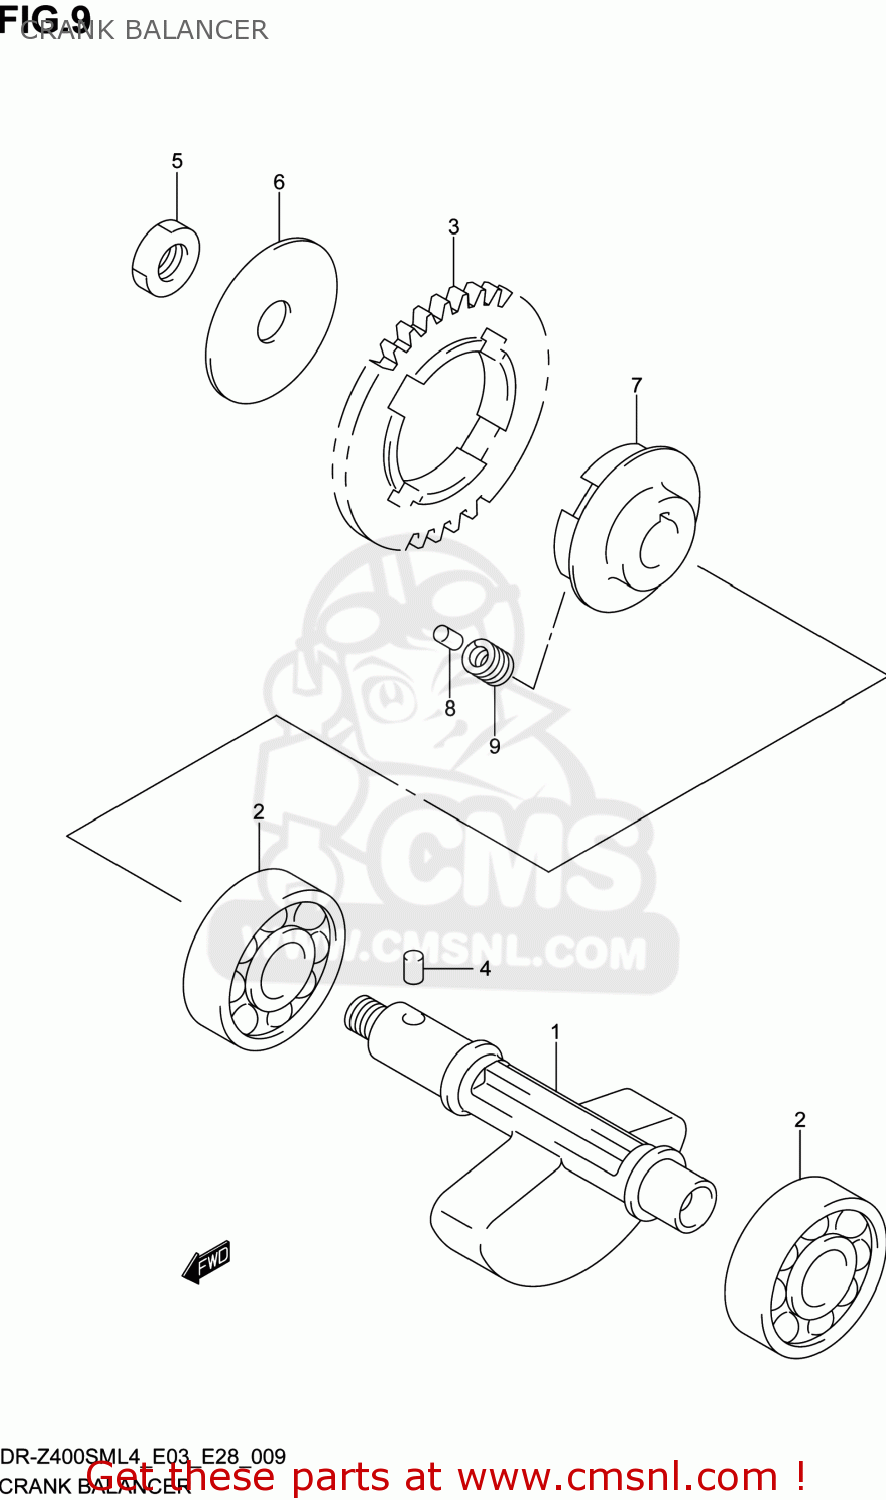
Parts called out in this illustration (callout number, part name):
1	BALANCER,CRANK
2	BEARING(15X42X13)
3	GEAR,CRANK BALANCER DRIVEN
4	PIN(5X8)
5	NUT
6	SHIM(12.2X47X1.6)
7	RACE,CRK BAL DRIVEN
8	PIN(4.5X9.5)
9	SPRING
